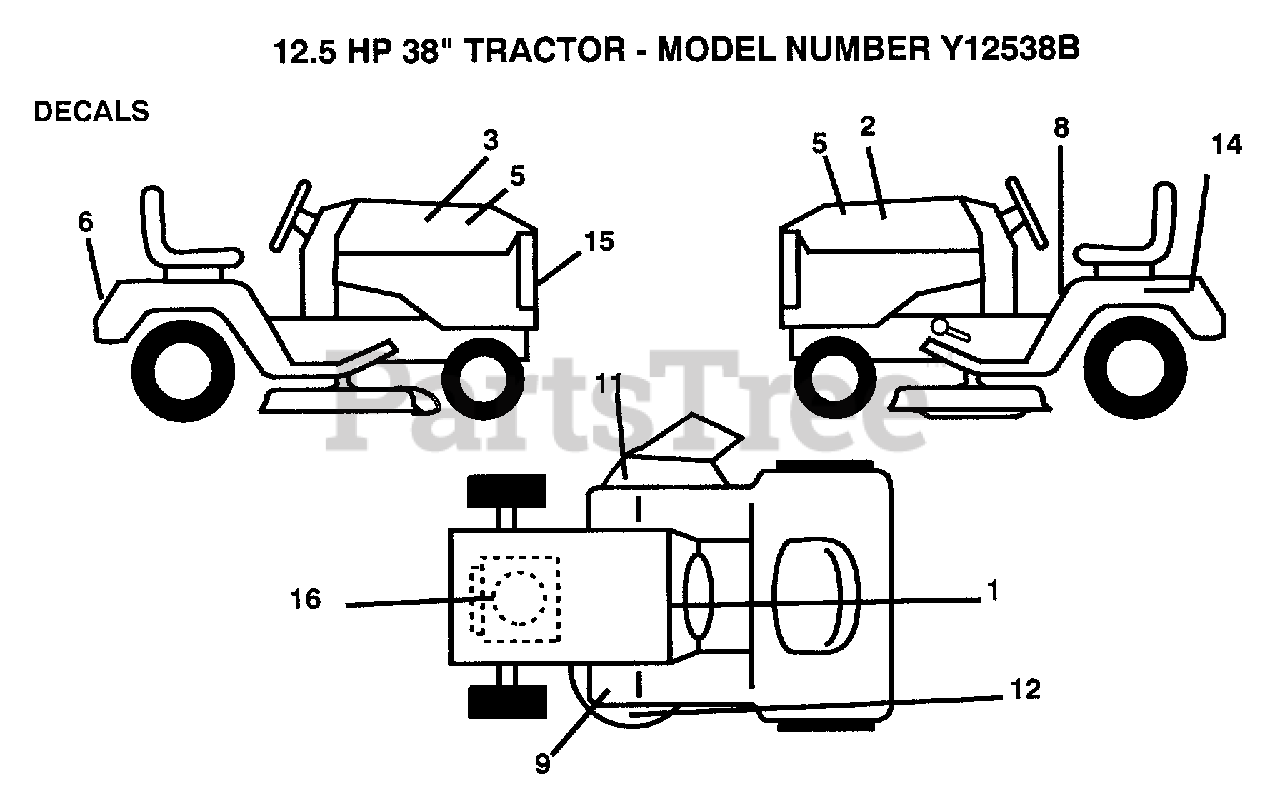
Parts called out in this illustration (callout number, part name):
8	DECAL
9	DECAL T
11	DECAL WARNING
12	DECAL YT
14	DECAL
